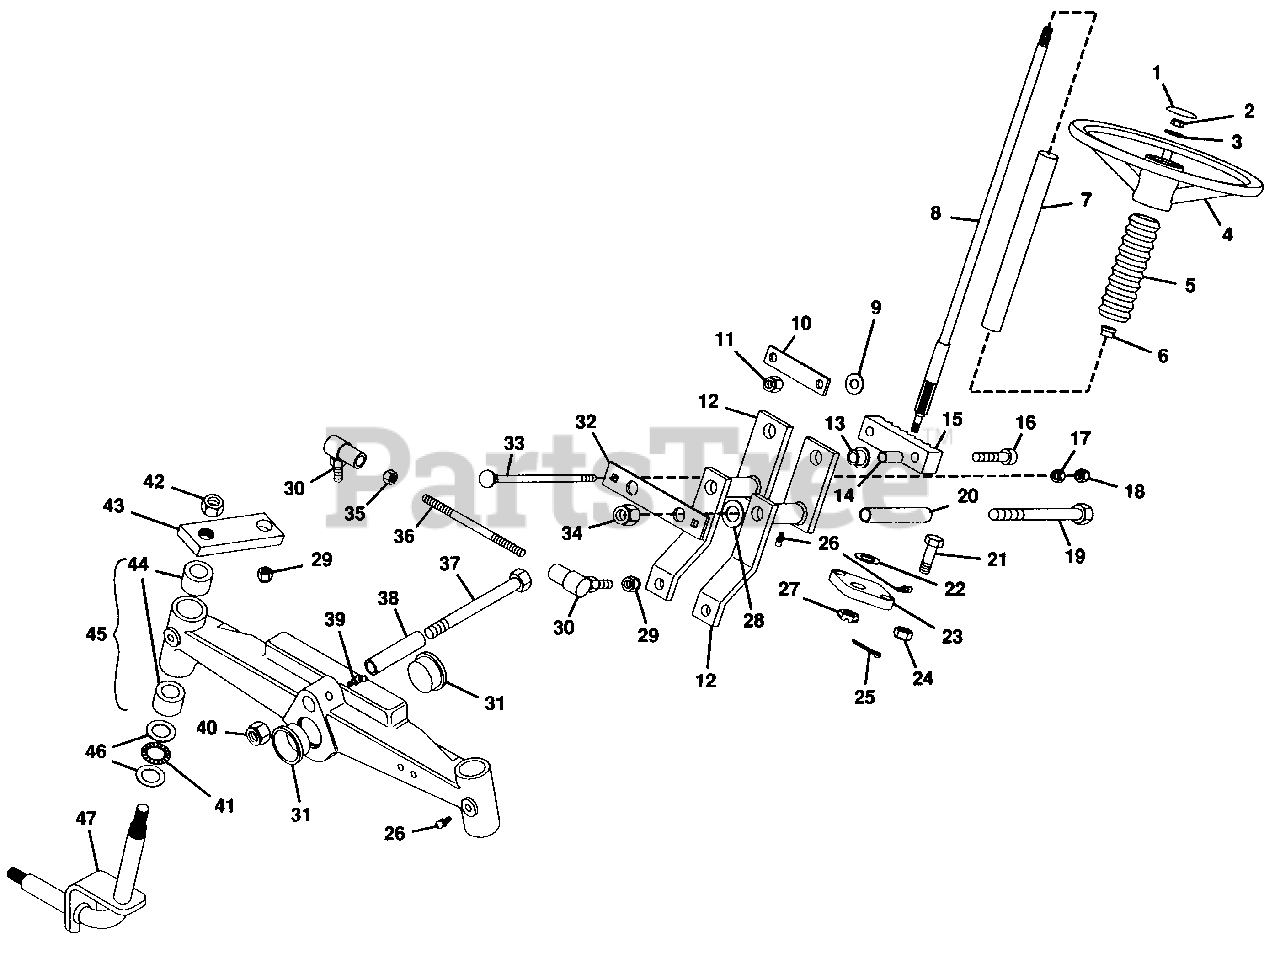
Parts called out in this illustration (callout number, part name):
1	CAP, STEERING WHEEL
2	NUT, JAM 5/8-11 HEX
3	WASHER, FLAT .656X1.312X.095
4	WHEEL, STEERING
5	BELLOWS, STEERING WHEEL
6	BUSHING, NYLON .760X1.00X.60 FLG
7	TUBE, PLASTIC 1.0 I.D.
8	SHAFT, STEERING
9	WASHER, FLAT .375X1.125X.065
10	STRAP, RACK AND PINION
11	NUT, LOCK 3/8-16
12	WELDMENT, STEERING
13	BEARING, FLANGE(P/M BRONZE)
14	BUSHING, .391X.622X.670
15	GEAR, RACK
16	SCREW, CAP 3/8-16X2.0 HSHD
17	NUT, HEX 5/16-18
18	NUT, LOCK 5/16-18
19	BOLT, HEX 1/2-13X6.0
20	SLEEVE, PIVOT
21	BOLT, HEX 7/16-14X1.5
22	RACE, THRUST
23	SUPPORT, STEERING SHAFT
24	NUT, LOCK 7/16-14
25	PIN, COTTER .09X1.00
26	FITTING, LUBE 1/4-28
27	NUT, HEX 1/2-13 SLOTTED
28	RACE, BRG THRUST .752X1.240X.095
29	NUT, LOCK 3/8-24
30	BALL JOINT, STEERING
31	CAP, FRONT AXLE
32	PLATE, ADJUSTMENT
33	BOLT, 5/16-18X5.5 RD HD SQ NK
34	NUT, LOCK 1/2-13
35	NUT, HEX 3/8-24
36	ROD, STEERING
37	BOLT, HEX 3/4-10X4.5
38	TUBE, AXLE PIVOT
39	FITTING, LUBE 45 DEG.
40	NUT, LOCK 3/4-10
41	BEARING, NEEDLE THRUST
42	NUT, HEX 5/8-11
43	ARM, TIE ROD AXLE
44	BUSHING, .877X1.004X1.0
45	AXLE, STEERING
46	RACE, BEARING THRUST
47	WELDMENT, KING PIN
